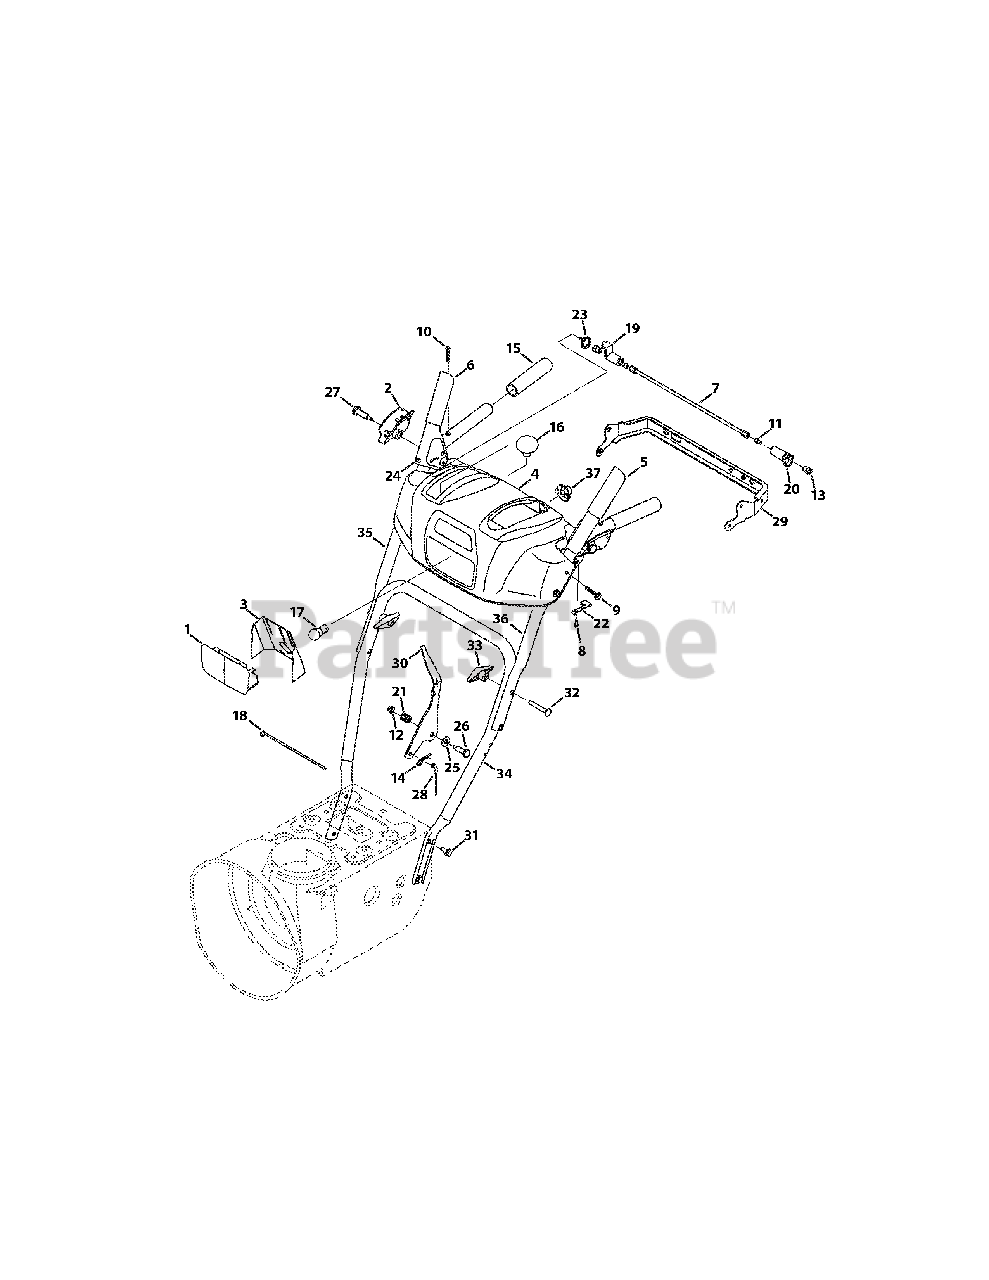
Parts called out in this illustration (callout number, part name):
2	Handle Clutch Lock - RH
2	Handle Clutch Lock - LH
3	Lens Reflector Label
4	T-Style Panel Ass’y, (inc. Ref. 1 & 3)
5	Handle Engagement Assembly LH
6	Handle Engagement Assembly RH
8	Screw, Plastite, 8-16 x .50
9	Screw, 1/4-20 x 1.625
10	Screw, #10-24 x 1.375
11	Screw, Socket, 1/4-20 x .50
12	Flange Lock Nut, 1/4-20
13	Shoulder Nut, 1/4-20
14	Click Pin
15	Handle Grip
16	Shift Knob
18	Cable Tie
20	Clutch Lock Cam
21	Compression Spring
22	Clutch Lock Spring
23	Torsion Spring
24	Rubber Bumper
25	Flat Washer, .385 x .87 x .06
26	Shoulder Screw, .374 x 1.05
27	Shoulder Screw, 1/4-20 x 1.345
28	Speed Selector Cable
31	Screw, 5/16-18 x .750
32	Carriage Screw, 5/16-18 x 2.25
33	Wing Knob
34	Lower Handle
35	Upper Handle RH
36	Upper Handle LH
37	Light Socket
